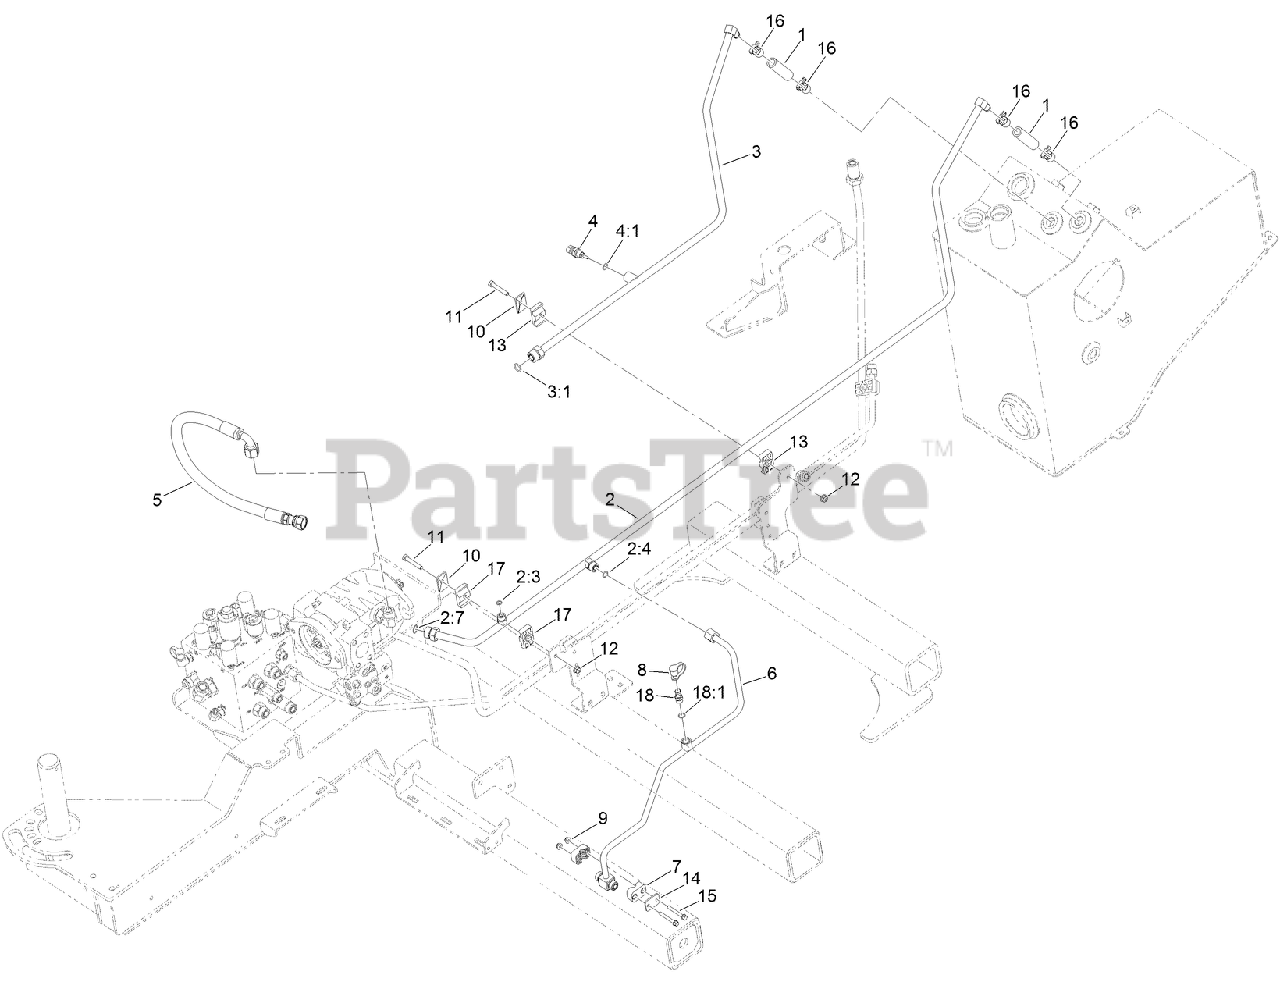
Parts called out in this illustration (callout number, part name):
2	TUBE ASM-HYD
2:3	O-RING
2:4	O-RING
2:7	O-RING
3	TUBE ASM
3:1	O-RING
4	SENDER-TEMPERATURE
4:1	O-RING
5	HOSE ASM-HYD
6	TUBE ASM
7	CLAMP-TUBE
8	CAP-DUST
9	NUT-HF
10	COVERPLATE
11	SCREW-HH
12	NUT-HF, NI
13	CLAMP-TUBE
14	PLATE-COVER, CLAMP
15	SCREW-HHF
16	CLAMP-HOSE, WORM DRIVE
17	CLAMP-TUBE
18	FITTING-DIAGNOSTIC
18:1	O-RING
